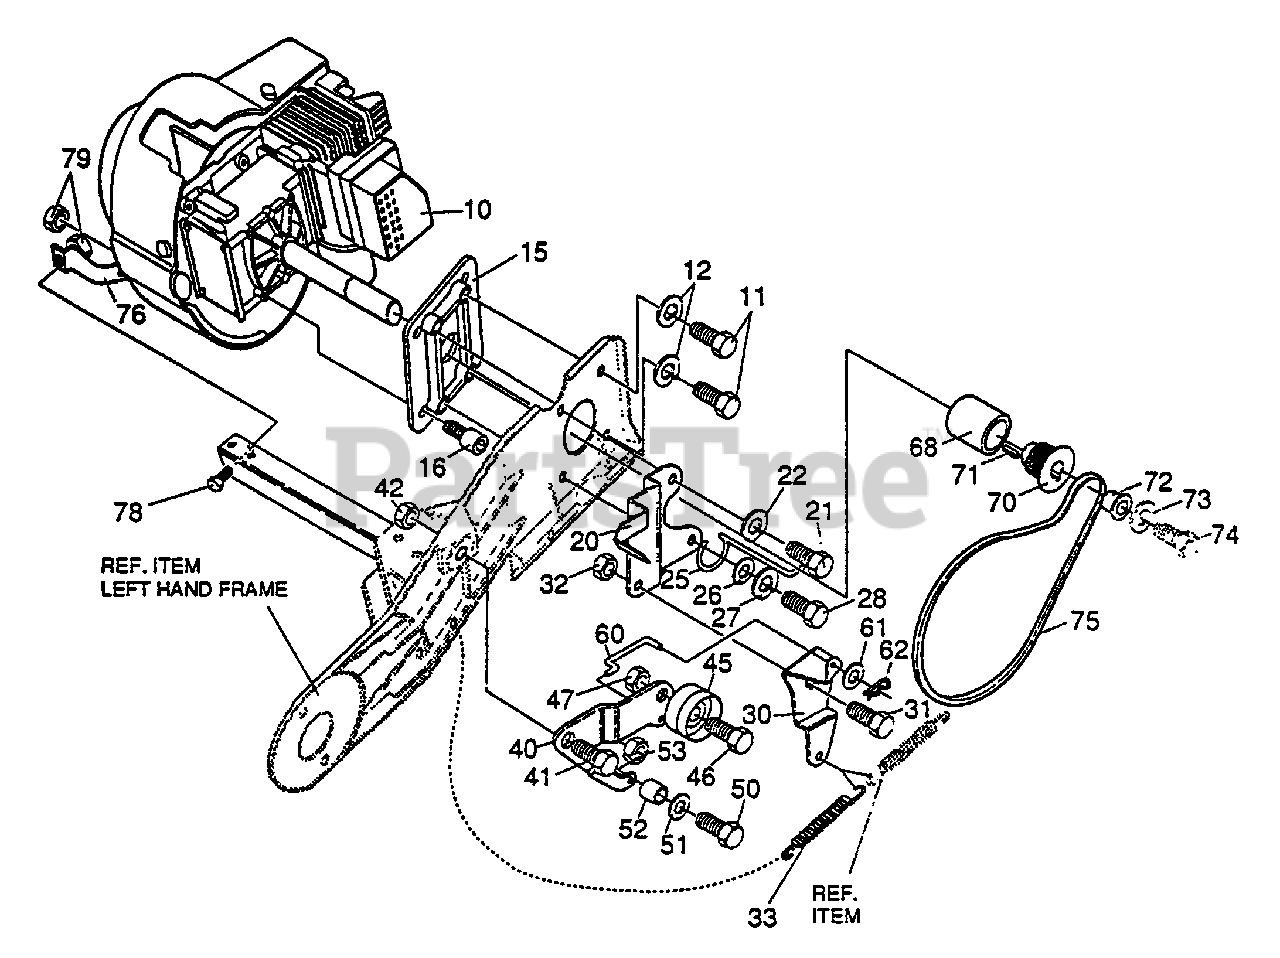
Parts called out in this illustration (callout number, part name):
11	SCREW, 5/16-24 X .63 HHC
12	WASHER HVSPTLK
15	PLATE, ENGINE ADAPTER
16	SCREW, 5/16-24 X 5/8
20	BRKT, IDLER PIVOT
21	SCREW, 5/16-24X .63
22	WASHER, HVSPTLK
25	GUIDE, BELT
26	FLATWASHER .344 X .69 X .065
27	WASHER, HVSPTLK
28	SCREW, 5/16-24 X 1.00
30	ARM, IDLER PIVOT
31	BOLT, .500 X .182
32	NUT, 5/16-18 REG HEX CTRLK
33	SPRING, EXT
40	ARM, IDLER
41	BOLT, .500 X .182 SHOULDER
42	NUT, 5/16-18 REG HEX CTRLK
45	PULLEY, IDLER
46	SCREW, 3/8-16 X 1.50
47	NUT, 3/8-16 HEX CTRLK JAM
50	SCREW, 1/4-20 X 1.50
51	FLATWASHER.281 X .63 X .065
52	ROLLER, BELT
53	NUT, 1/4-20 REG HEX CTRLK
60	ROD, CLUTCH
61	FLATWASHER .188 X .38 X .040
62	PIN, COTTER
68	OPTIONAL
70	PULLEY, ENGINE
71	KEY, SQUARE
72	PLUG, ENGINE PULLEY
73	WASHER, HVSPTLK
74	SCREW, 5/16-24 X 1.00
75	BELT, POLY-V
76	BRACKET, ENGINE SUPPORT
78	SCREW, 5/16-18 X .63
79	NUT, 5/16-18 REG HEX CTRLK
